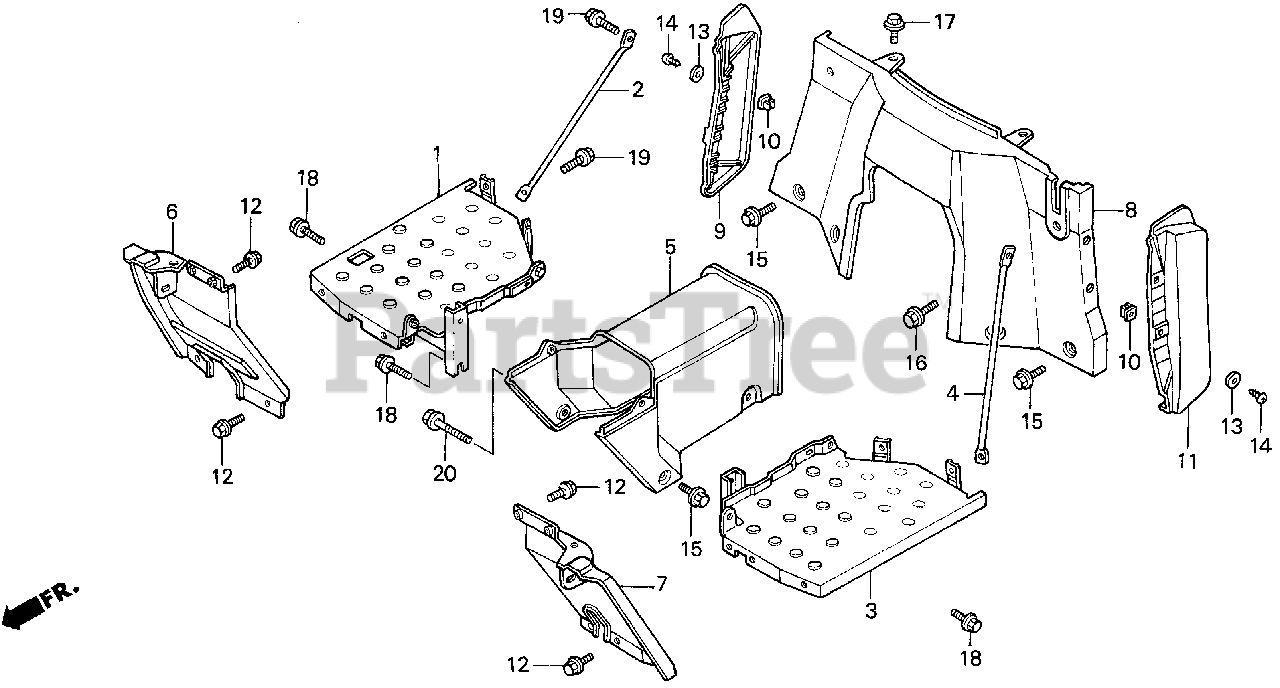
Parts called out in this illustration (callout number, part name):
1	STEP, R. *R165* (JOLLY RED)
2	ROD, R. STEP TENSION
3	STEP, L. *R136* (DIANA RED)
4	ROD, L. STEP TENSION
5	FLOOR *R136* (DIANA RED)
6	FENDER, R. FR. *R136* (DIANA RED)
7	FENDER, L. FR. *R136* (DIANA RED) (NOT AVAILABLE)
8	COVER, RR. *R136* (DIANA RED)
9	COVER, R. SIDE *R165* (JOLLY RED)
10	NUT, NYLON (6MM)
11	COVER, L. SIDE *R165* (JOLLY RED)
12	BOLT, FENDER (6X18)
13	WASHER (6MM)
14	SCREW, TAPPING (6X20)
15	BOLT, FLANGE (6X12)
16	BOLT, FLANGE (6X12)
17	BOLT, FLANGE (6X12)
18	BOLT, FLANGE (8X14)
19	BOLT, FLANGE (8X16)
20	BOLT, FLANGE (6X20)
